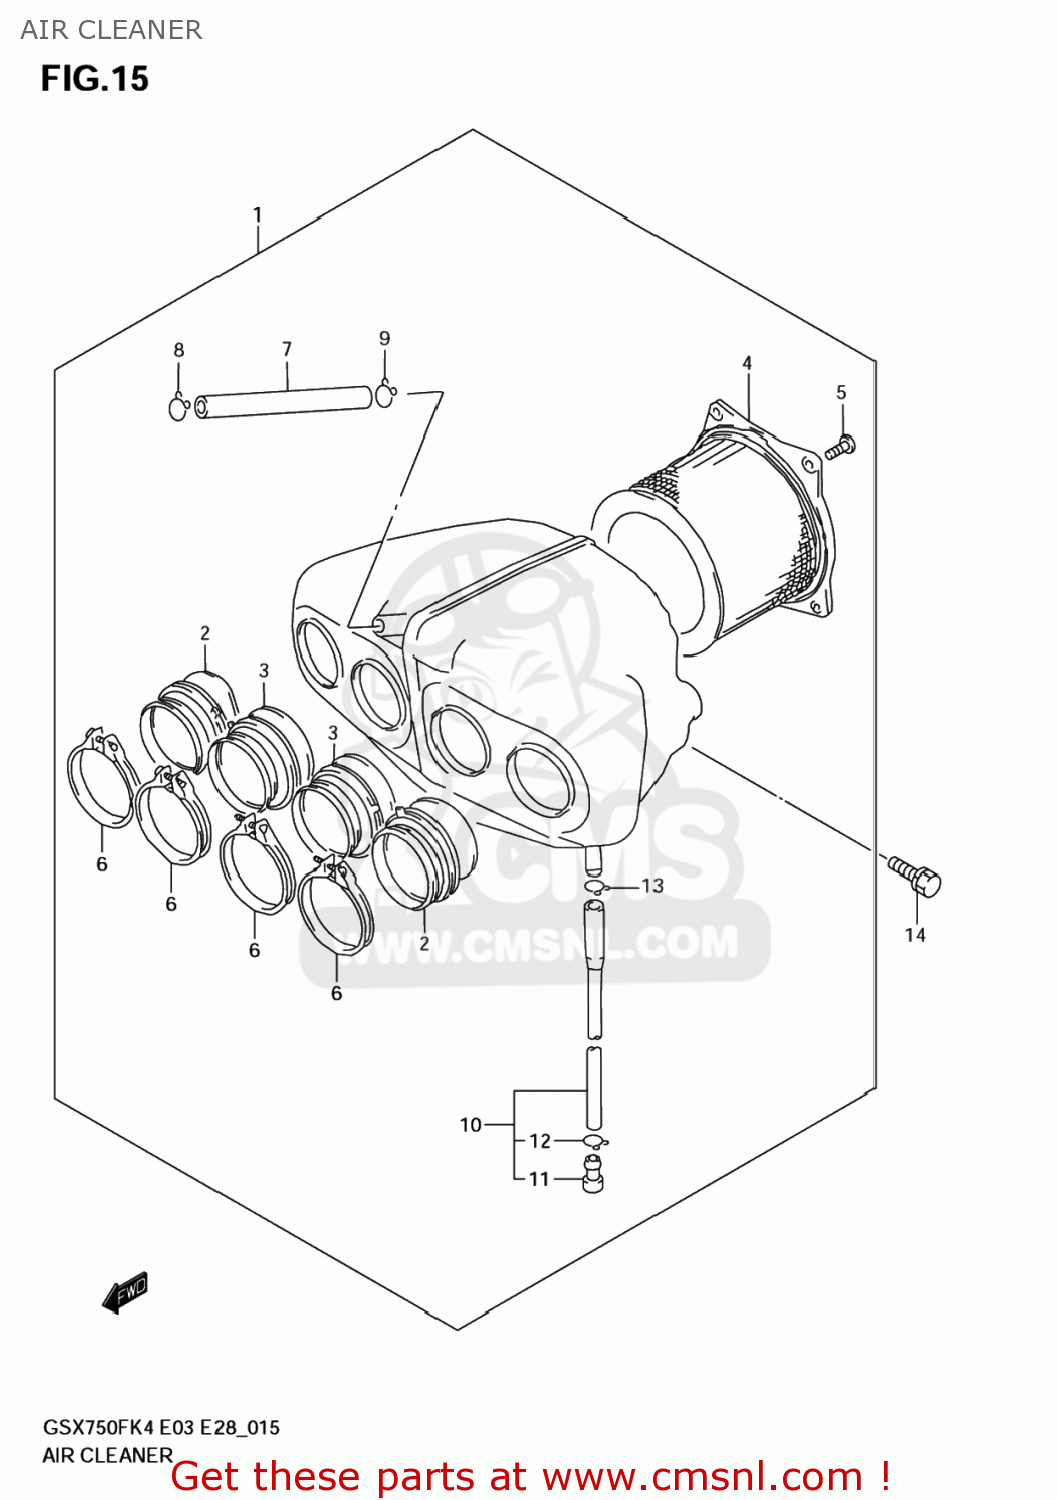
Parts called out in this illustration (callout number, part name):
1	CLEANER ASSY,AIR
2	TUBE,OUTLET,L/R
3	TUBE,OUTLET ML/MR
4	FILTER ASSY
5	SCREW 5X12
6	CLAMP
7	TUBE,BREATHER
8	CLIP
9	CLIP
10	TUBE,DRAIN
11	STOPPER,DRAIN
12	CLIP
13	CLIP
14	BOLT
